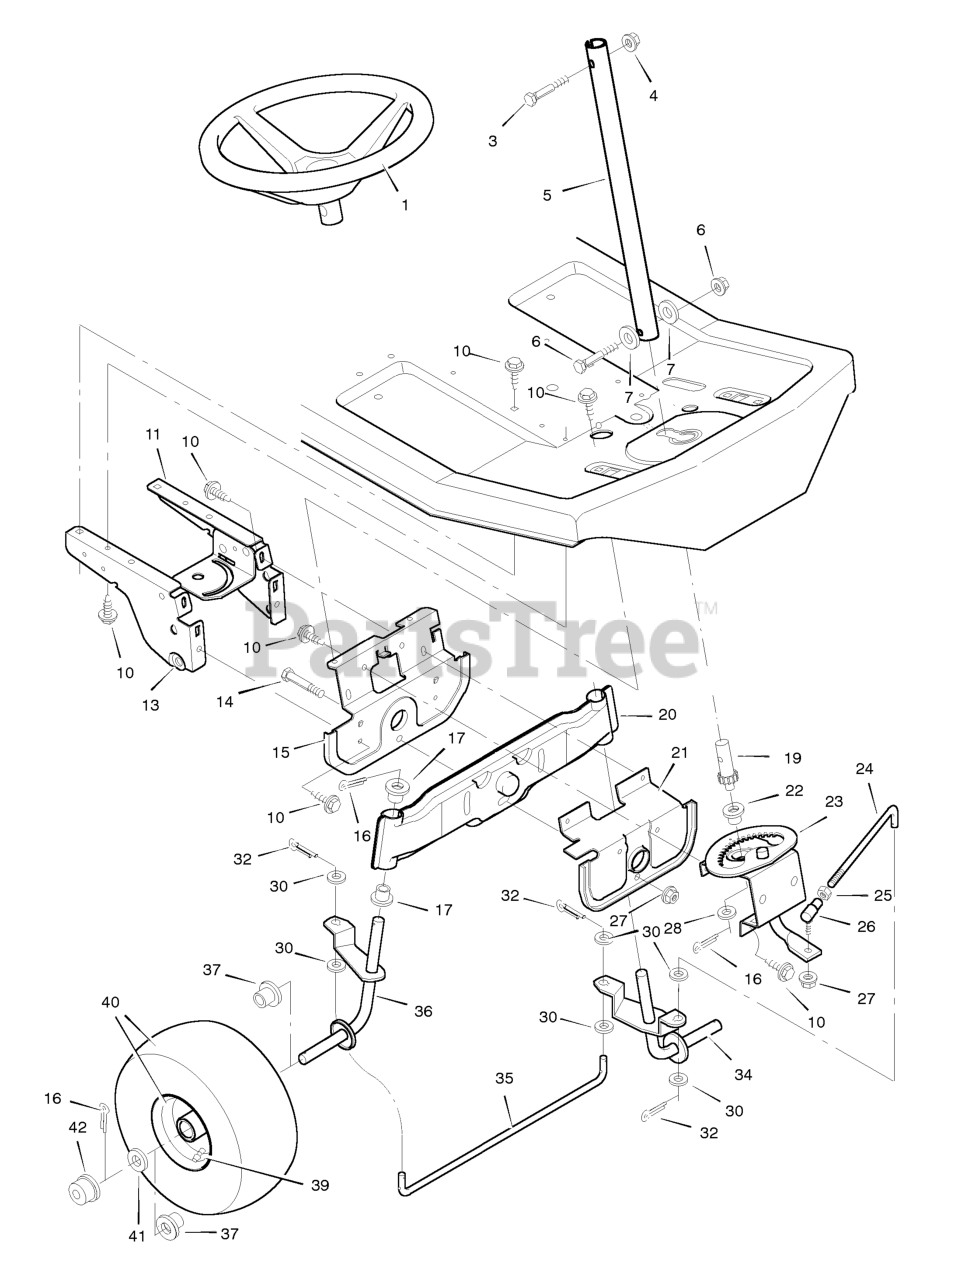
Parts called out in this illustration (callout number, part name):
1	Steering Wheel
3	Bolt, Hex
4	Locknut, Flange
5	Post, Steering
6	Nut, Hex
7	Washer
8	Cover, Steering Post
9	Bearing
11	Plate, Left Suspension
13	Plate, Right Suspension
14	Bolt, Hex
15	Support, Front Axle
16	Pin, Cotter
17	Bearing, Spindle
19	Gear, Pinion
20	Axle Assembly, Front
21	Hanger Assembly, Front Axle
22	Bearing
23	Sector Assembly
24	Rod, Drag Link
25	Nut, Hex
26	Ball Joint, Steering
27	Locknut, Flange
32	Pin, Cotter
34	Spindle Assembly, Left
35	Rod, Tie
36	Spindle Assembly, Right
37	Bearing, Wheel
39	Valve Stem
40	Wheel & Tire Assembly
42	Cap, Hub
